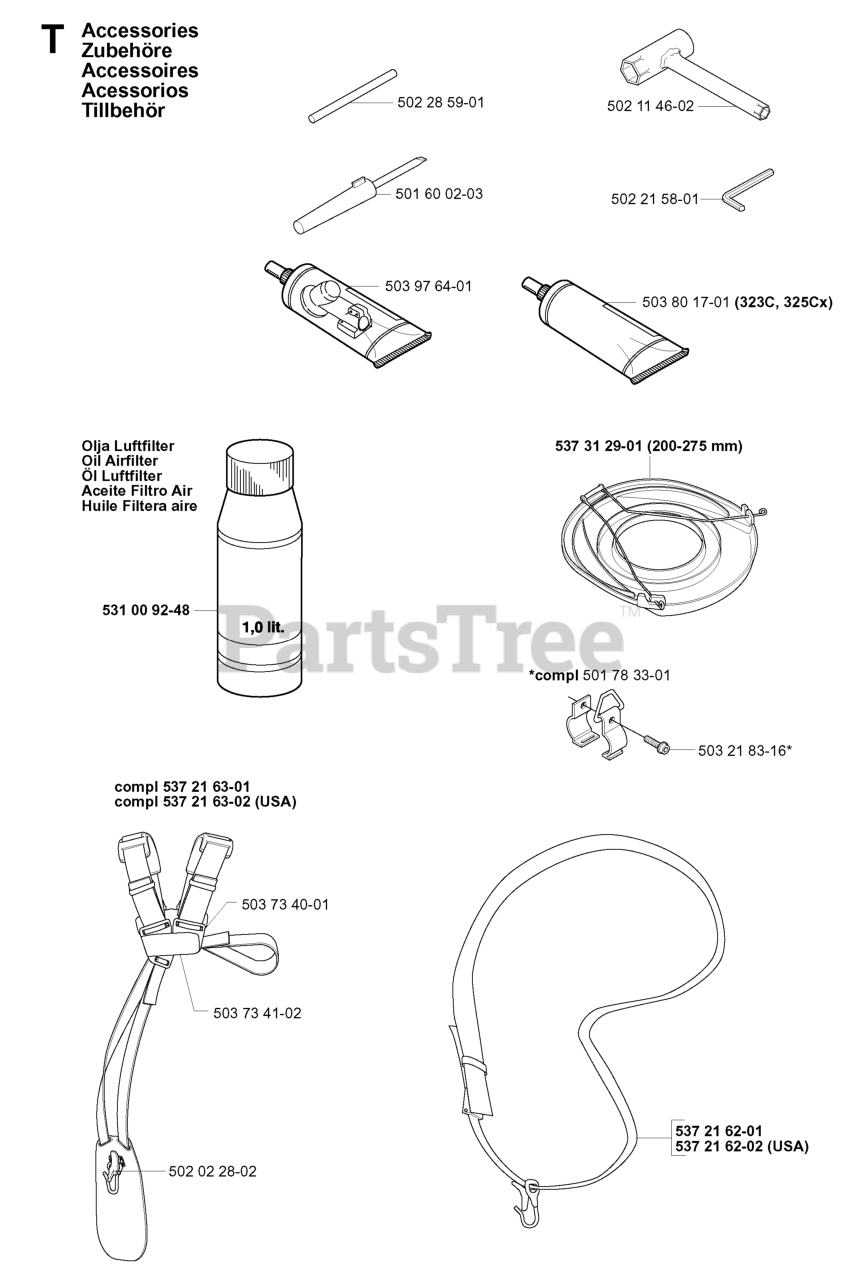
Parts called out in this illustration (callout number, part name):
1	PANEL.CONTROL.SNOW.BLACK
2	LEVER.CONTROL.LH.PL.BLACK
3	LEVER.CONTROL.RH.PL.BLACK
4	BAIL.CONTROL.INTERLOCK.SNOW
5	BRACKET.ARM.IMPELLER.ROD.YZ
6	BOLT
7	SPACER.CONTROL.LEVER
9	KNOB.OVERMOLD.DS.HUSQVARNA/BLK
10	KNOB.HANDLE.3/8.TRI-POINT.BLAC
11	WASHER
12	BOLT 3/8-16 X 2-1/4
13	SPRING RETAINER
